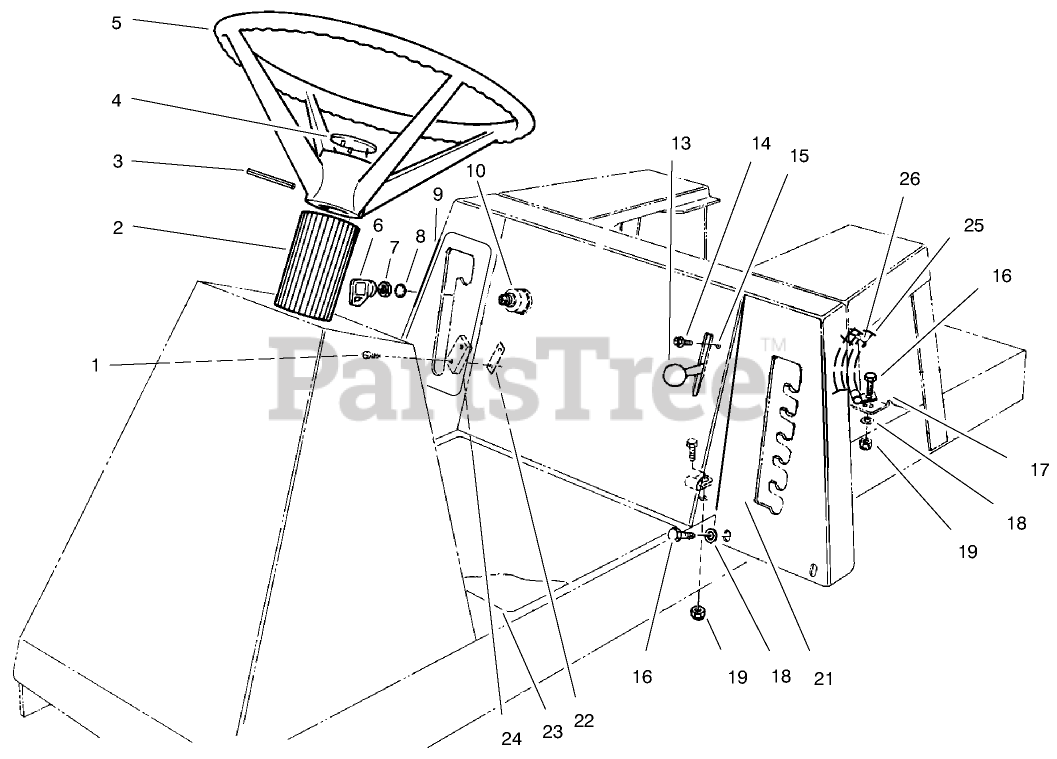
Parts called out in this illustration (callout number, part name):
1	SCREW-PPHTF
2	COVER-STEERING SHAFT
3	PIN-ROLL
4	INSERT - STEERING WHEEL, WH EMBLEM
5	STEERING WHEEL ASM
6	KEY-IGNITION
7	NUT-HH
8	WASHER-LOCK
9	DECAL - DECK ENGAGE
10	STARTER SWITCH ASM
13	KNOB-CONTROL
14	SCREW-HWHTF
16	SCREW-HH
17	CLIP
18	WASHER-PLAIN
19	NUT-LOCK, NI
21	DECAL - HOC
22	NUT-SPEED
23	DECAL - INSTRUCTION
24	SWITCH-MICRO
25	WIRE ASM
26	TIE-CABLE
